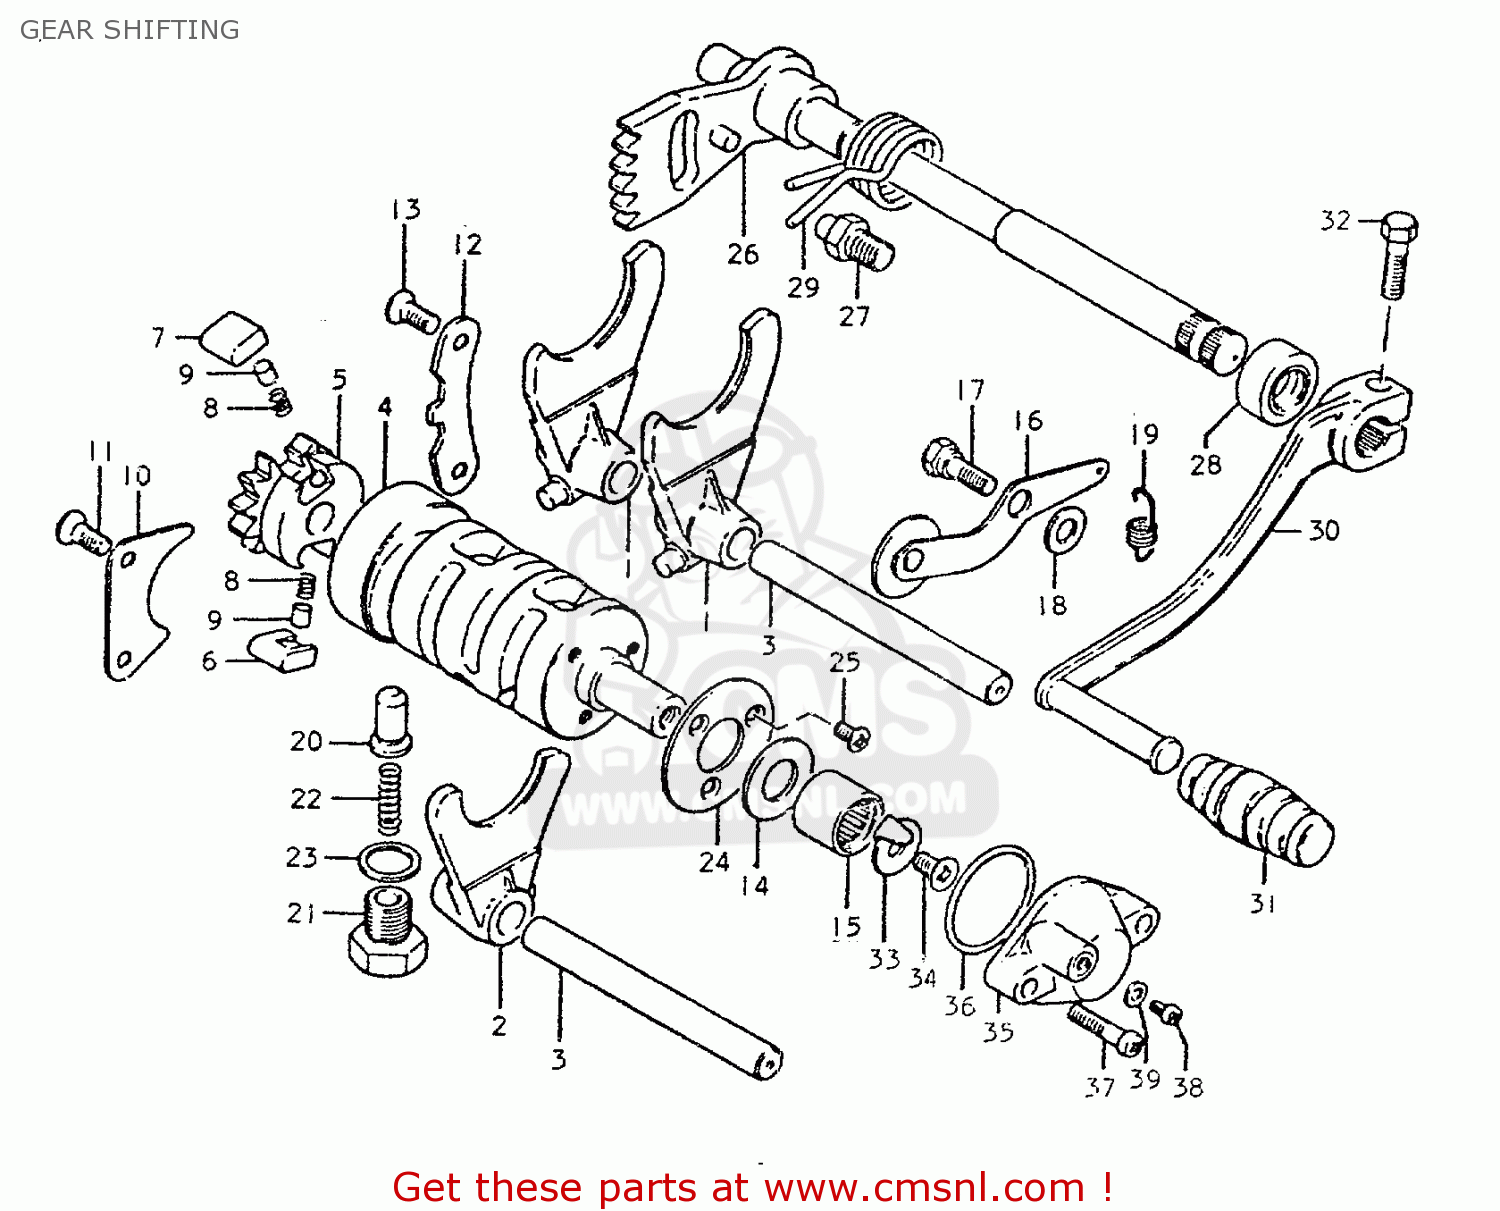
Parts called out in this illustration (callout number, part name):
1	FORK,GEAR SHIFT NO.1
2	FORK,GEAR SHIFT NO.3
3	SHAFT,GEAR SHIFT FORK
4	CAM,GEAR SHIFT
5	RETAINER,GEAR SHIFT CAM
6	PAWL,GEAR SHIFT NO.1
7	PAWL,GEAR SHIFT NO.2
8	SPRING
9	PIN(5X8)
10	LIFTER,GEAR SHIFT PAWL
11	SCREW
12	GUIDE,GEAR SHIFTING CABLE
13	SCREW
14	WASHER
15	ROLLER BEARING (12X18X1
16	STOPPER,GEAR SHIFTING
17	BOLT(6X16.1)
18	WASHER
19	SPRING
20	STOPPER,GEAR SHIFT CAM NO.2
21	HOLDER,GEAR SHIFT CAM STOP SPR
22	SPRING
23	GASKET(14X19.2X2) (NAS)
24	PLATE,GEAR SHIFT CAM STOPPER
25	SCREW 4X12
26	27
27	STOPPER,GEAR SHIFT CAM
28	OIL SEAL
29	SPRING
30	LEVER ASSY,GEAR SHIFT
31	RUBBER,GEAR SHIFT PEDAL
32	BOLT
33	CONTACT,GEAR SHIFT SWITCH
34	SCREW
35	BODY,GEAR SHIFT SWITCH
36	O RING(D:1.9,ID:27.7)
37	SCREW 5X20
38	SCREW
39	WASHER
